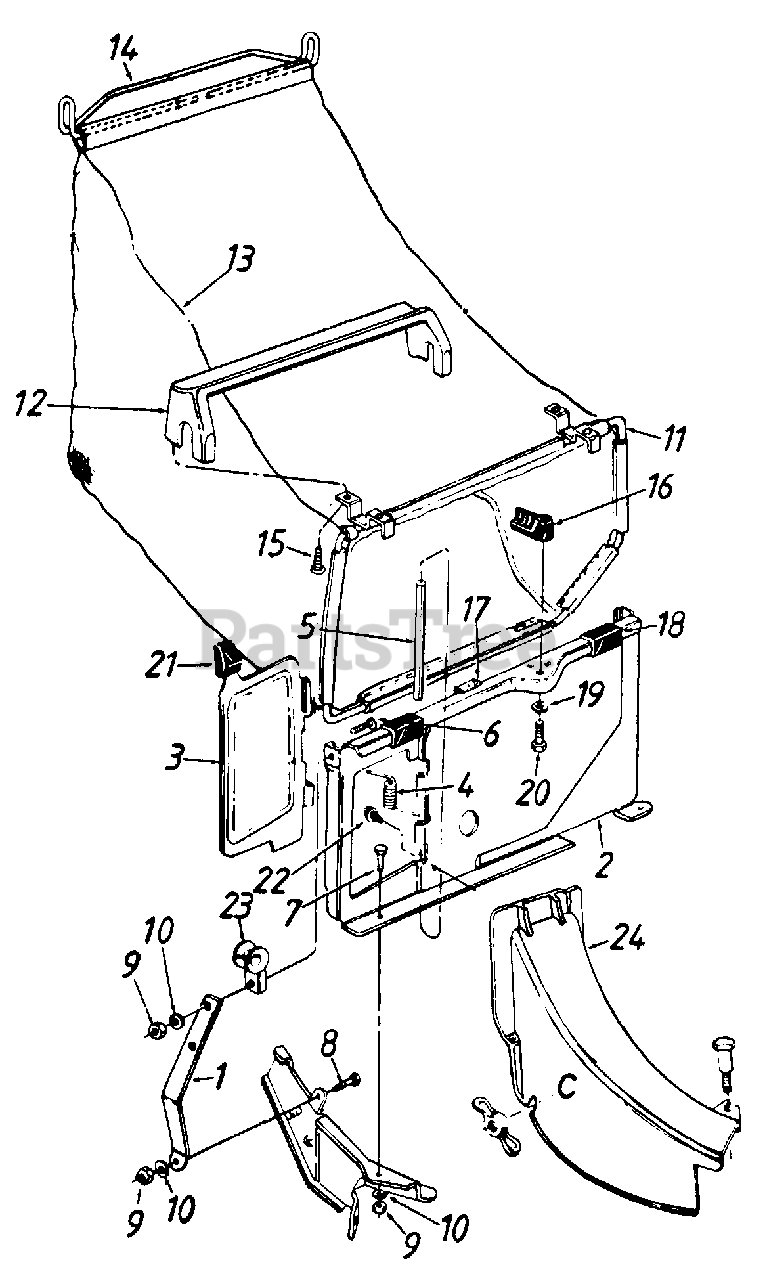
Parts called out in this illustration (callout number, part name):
1	BRACKET-PANEL SUP
2	PANEL ASSY-CATCHER
3	DOOR-TOP DISCHARGE
4	DOOR-TOP DISCHARGE
6	SCREW-TRUSS MACH
7	SCREW-HEX 1/4-20 x .50
8	SCREW-HEX 1/4-20 C .62
9	NUT-HEX 1/4-20
10	LOCK WASHER 1/4 DIA
11	FRAME-GRASSCATCHER
12	HANDLE-BAG-BLACK
13	BAG-GRASS-CONV
14	HANDLE-GRASSCATCHER
15	SCREW-TAP .215 x 1
16	KNOB-LOCKING
17	STRIP-FOAM 1/4X1.0
18	CLIP-PANEL BAG
19	WASHER-SHAKE PROOF
20	SCREW-HEX 1/4-20 C .62
21	KNOB
22	SCREW-HEX B-TAP #10 x .38
23	GUIDE-ROPE
24	CHUTE ASSY-TOP DISCH
